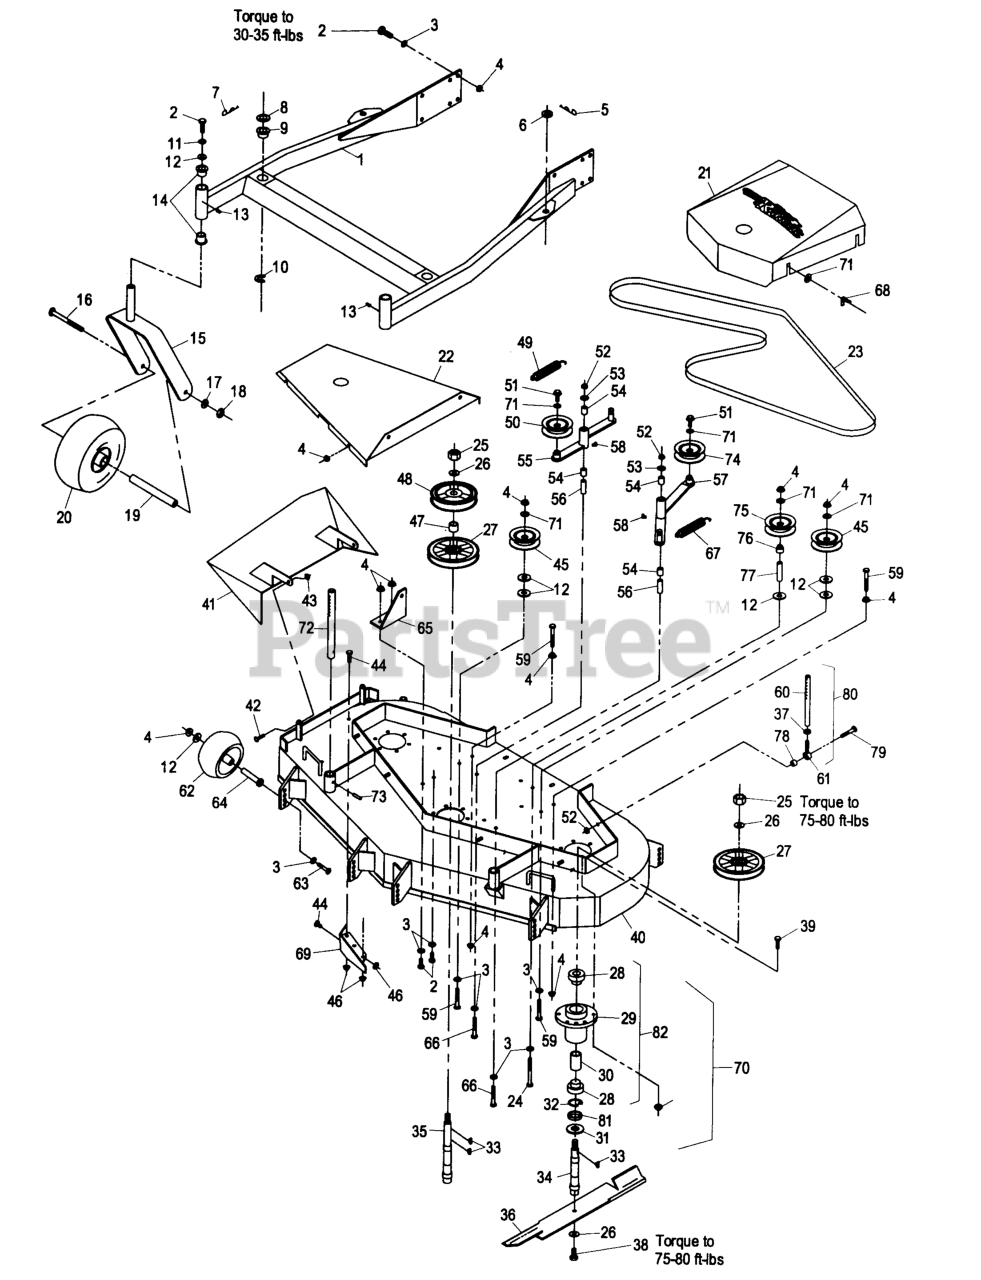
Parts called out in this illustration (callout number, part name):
5	PIN,HAIR COTTER
8	SPACER-DECK SUPPORT
9	BUSHING-DECK
12	WASHER
14	BEARING-FLANGED
21	COVER W/DECAL TR/FMD523
23	BELT,BLADE DRIVE
26	WASHER-SPRING
27	SHEAVE,BLADE DRIVE
28	BEARING
30	SPACER-BEARING
31	GUARD-BEARING, BOTTOM
34	SHAFT,SPINDLE SHORT
35	SHAFT,SPINDLE LONG
41	WLD,CHUTE DISCHARGE
45	IDLER,PULLEY
47	SPACER-TUBE
48	SHEAVE,MOWER DRIVE
49	SPRING-EXTENSION
50	IDLER,PULLEY
54	SLEEVE-BEARING
55	ASM,IDLER ARM
56	BUSHING-PIVOT, IDLER
57	ASM,IDLER ARM
60	LINK, DECK SUPPORT
61	BALLJOINT
62	ROLLER-SCALP, ANTI
64	BUSHING-ROLLER
65	BRACKET,SPRING ANCHOR
66	SCREW-HH
67	SPRING-EXTENSION
68	NUT-WING
69	WLD,BAFFLE DISCHARGE
70	CUTTER HOUSING ASSY,CEN
72	ROD,DECK SUPPORT
74	PULLEY-IDLER
75	PULLEY-IDLER
76	BUSHING,IDLER
77	SPACER-FENDER
81	SPACER-PULLEY/BEARING
